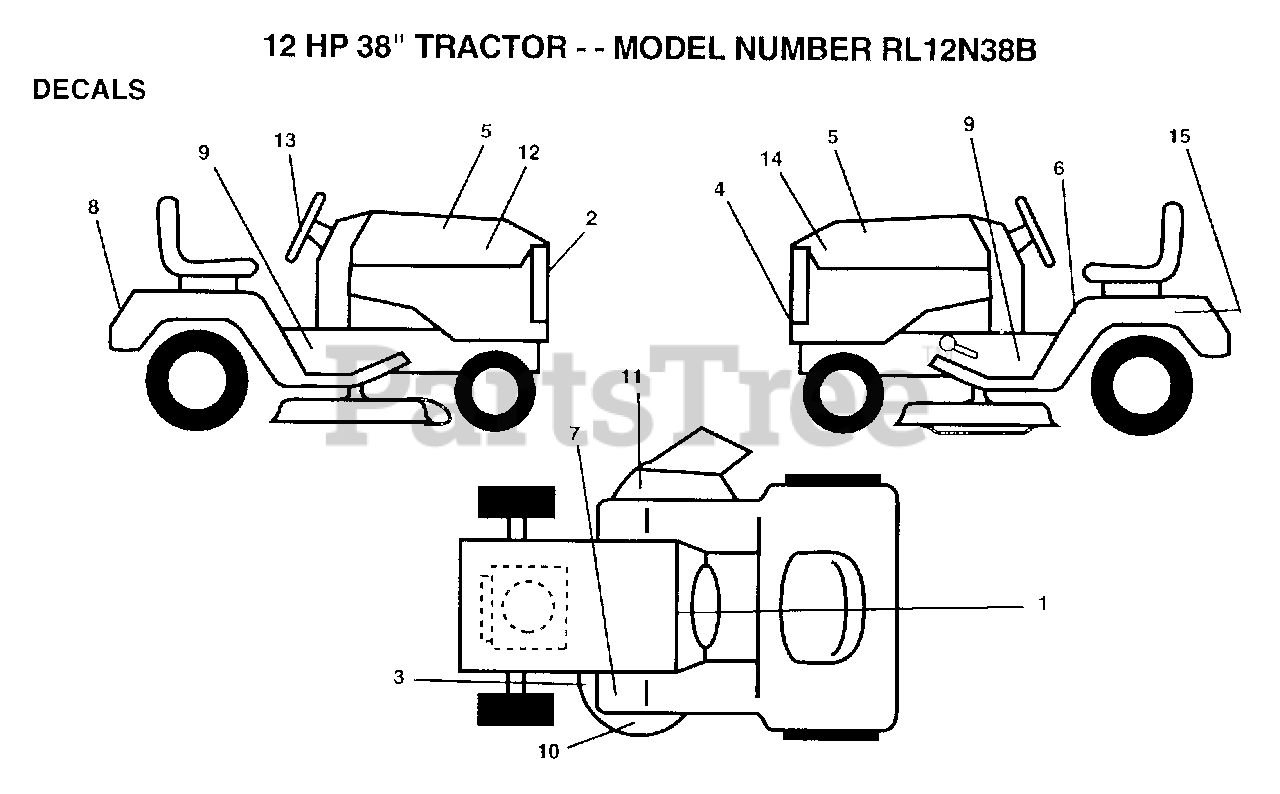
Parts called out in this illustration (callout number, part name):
2	GRILL DECAL
3	DECAL
6	DECAL CAUTION
7	DECAL T
8	FENDER DECAL
9	DECAL CHASSIS SPEED DECK
11	"DECAL, WARNING"
13	"DECAL,STR WHL"
15	DECAL
